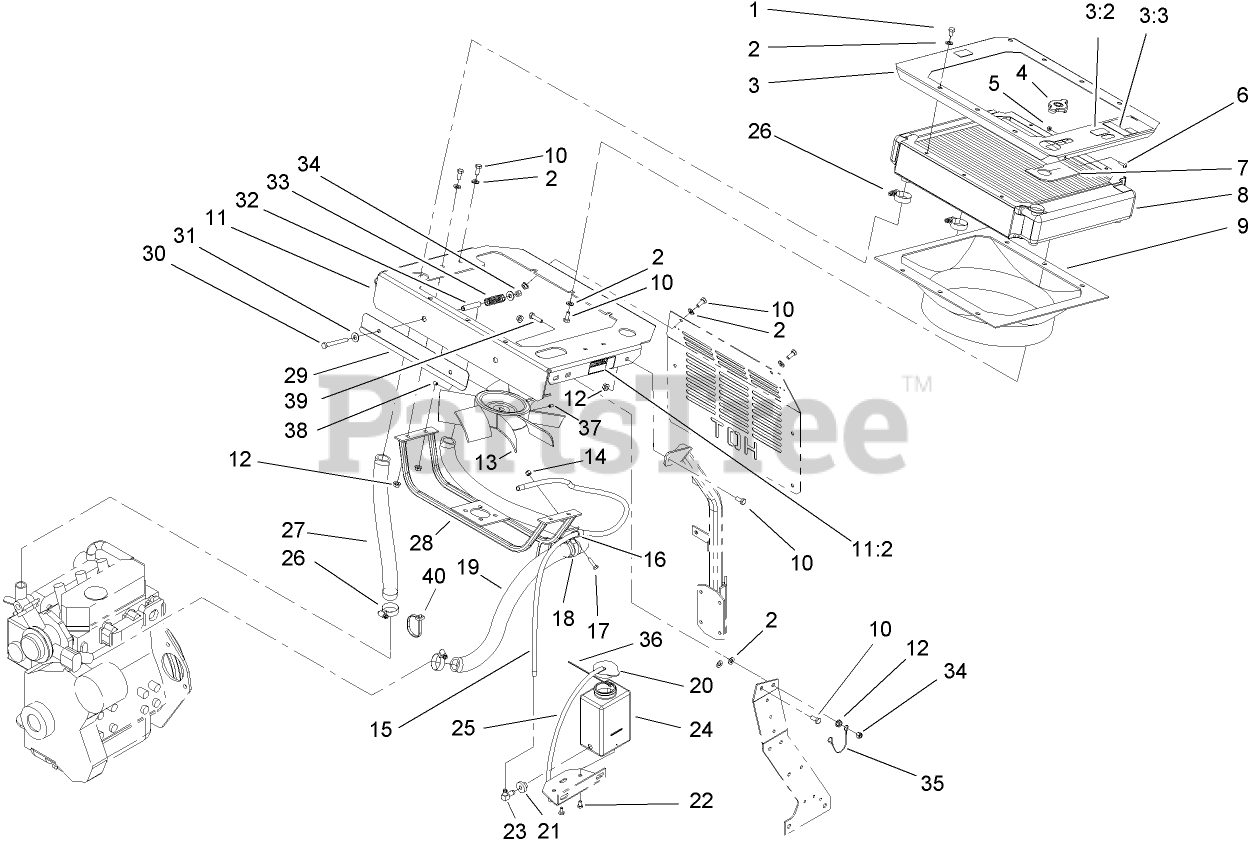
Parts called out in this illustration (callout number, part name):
1	SCREW-HH
2	WASHER-PLAIN
3	PLATE-TRIM, RADIATOR
3:2	DECAL-SURFACE, HOT
3:3	DECAL-COOLANT
4	CAP-RADIATOR
5	NUT-LOCK, NI
6	SCREW-HEAD, TRUSS
7	SHIELD-FILL NECK, RADIATOR
8	RADIATOR
9	SHROUD-COOLING, ENGINE
10	SCREW-HH
11	FAN MOUNTING PLATE ASM
11:2	DECAL-FAN, RADIATOR
12	NUT-HF
14	NUT-LOCK, NI
16	CLIP-LOOM
17	SCREW-HH
18	CLIP-LOOM
19	HOSE-INLET, ENGINE
20	CAP-TANK, OVERFLOW
21	BUSHING-VALVE, FUEL
22	SCREW-HH
23	FITTING-ELBOW
24	TANK-OVERFLOW
26	CLAMP-HOSE
27	HOSE-OUTLET, ENGINE
28	MOUNT-MOTOR, FAN
29	BRACKET-DEFLECTOR, AIR
30	SCREW-HH
31	WASHER-FLAT
32	SPACER
33	SPRING-INDICATOR, REVERSE
34	NUT-LOCK, NI
35	LANYARD
36	TIE-CABLE
37	SCREW-SET
38	SCREW-SET
39	SCREW-HH
40	TIE-PLASTIC
